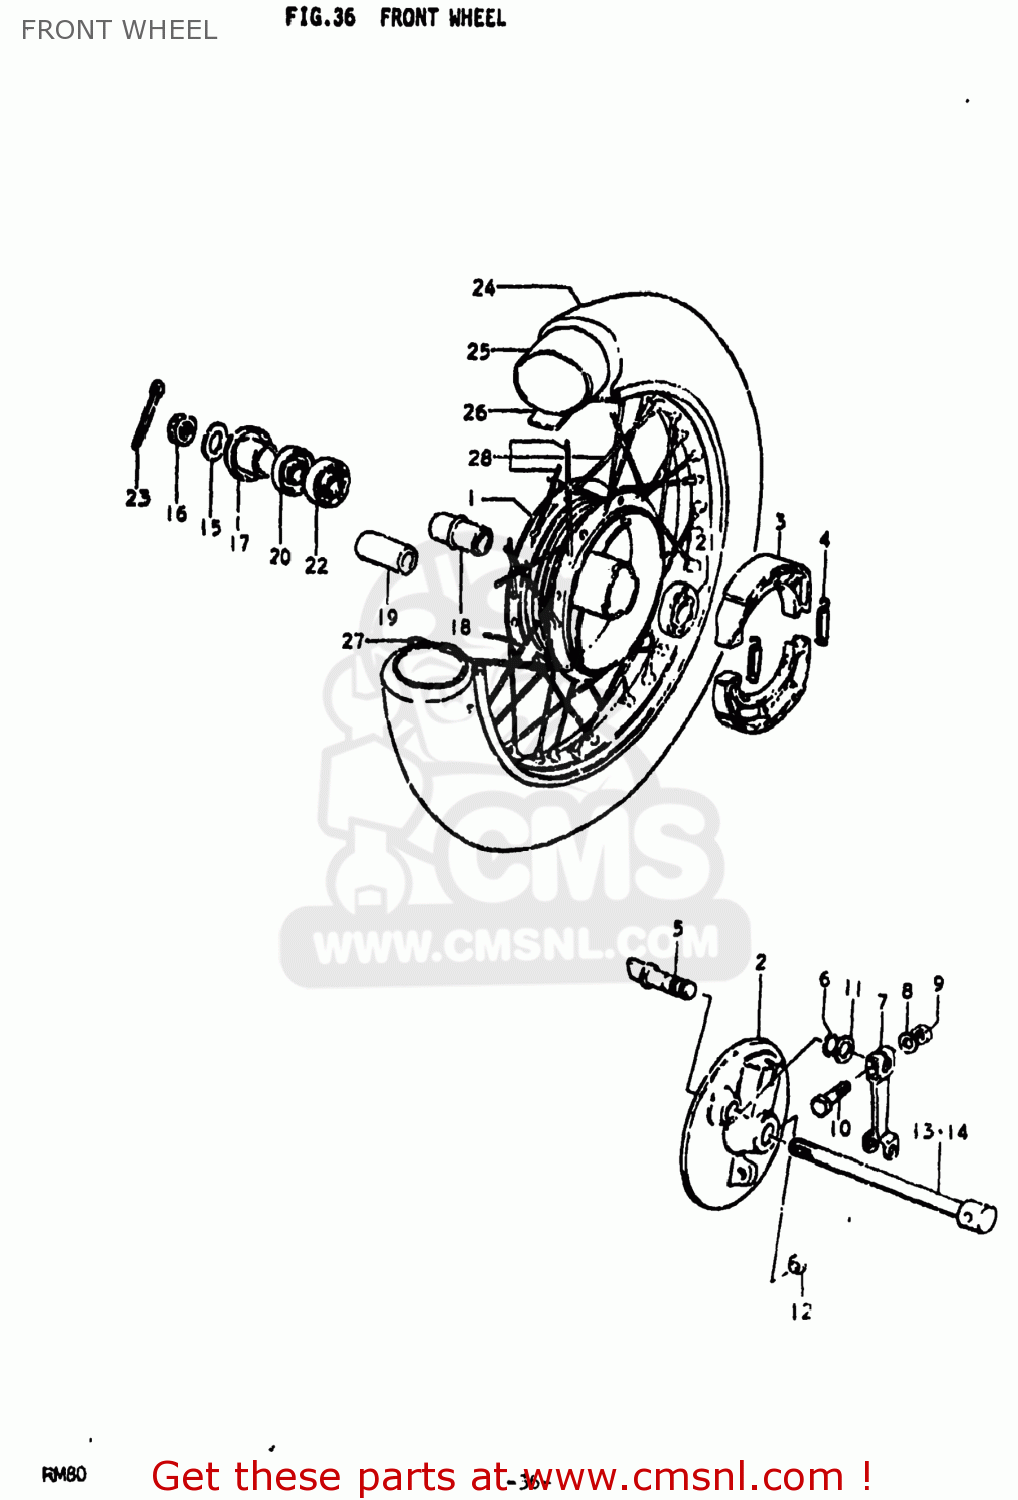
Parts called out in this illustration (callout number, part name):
1	HUB,FRONT
2	PANEL,FRONT HUB
3	SHOE,BRAKE
4	SPRING(L:34)
5	CAM,FR BRAKE
6	O RING(D:2.5,ID:11.4)
7	LEVER,FRONT BRAKE CAM
8	WASHER
9	NUT
10	BOLT
11	WASHER(12.5X20X1)
12	CAP(OD:17)
13	AXLE,FRONT
14	AXLE,FRONT
15	WASHER
16	NUT
17	SPACER,FRONT AXLE,RIGHT
18	SPACER,FRONT HUB BEARING
19	SPACER (10.2X16X51)
20	SEAL,OIL(15X31X5)
21	BEARING, LH
22	BEARING
23	PIN 20X20
24	TIRE,FRONT
25	TUBE,INNER
26	PROTECTOR,WHEEL,INNER
27	RIM,FRONT WHEEL
28	SPOKE SET
